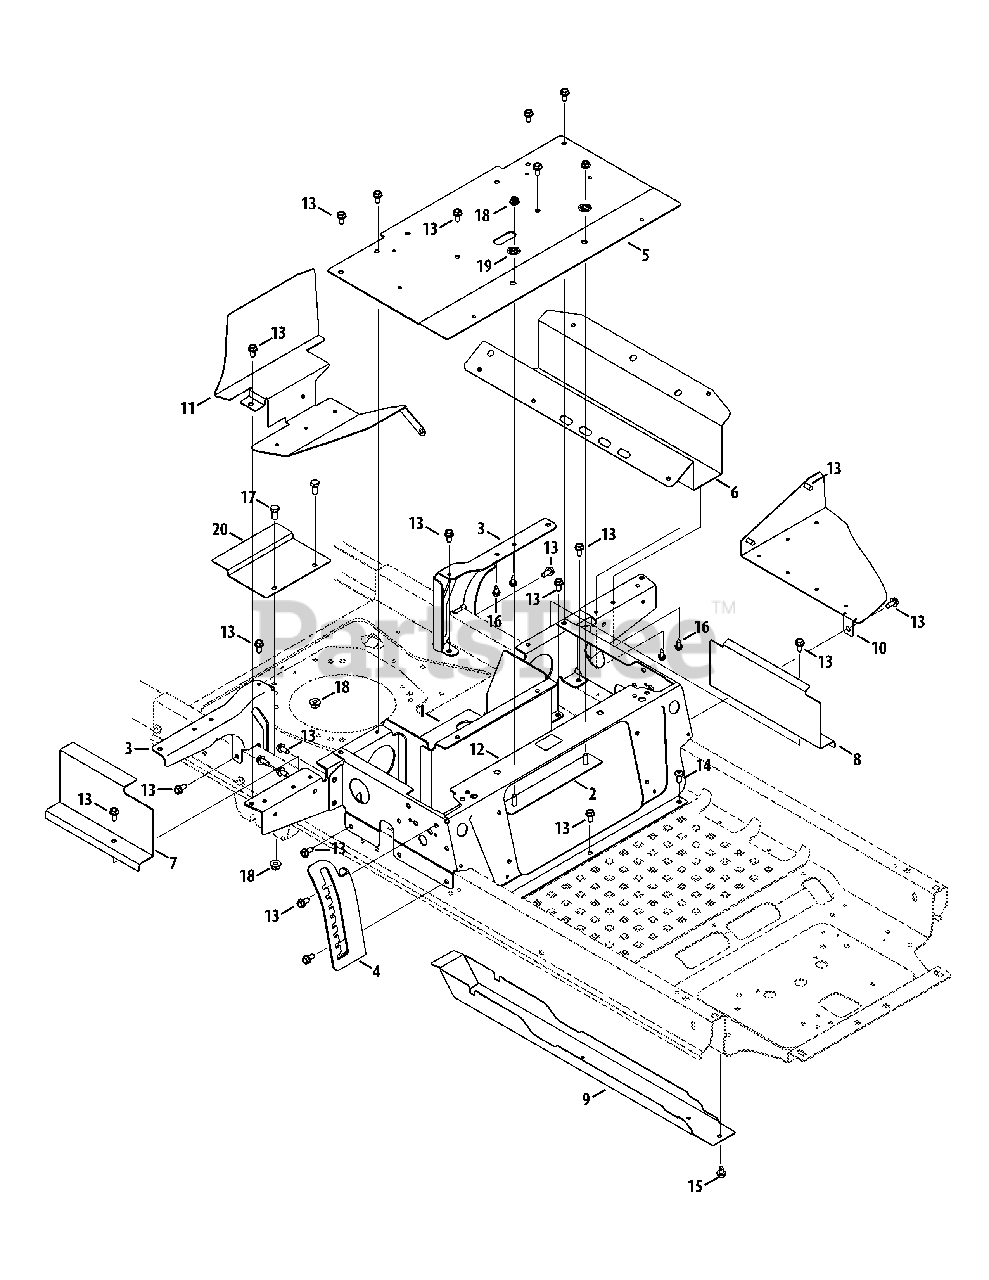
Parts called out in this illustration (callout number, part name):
1	Seatbox Brace, Rear
2	Seat Bolt Weldment
3	Rear Tank Bracket
4	Height Index Bracket
6	Control Panel Mounting Plate
7	Shield Bracket, RH
8	Shield Bracket, LH
9	Shield Bracket, Main Harness
10	Shield Bracket, Control
11	Shield Bracket, RH Pod
13	Hex Washer Screw, 5/16-18 x .750
14	Self Tapping Screw, 5/16-18 x .750
15	Hex Washer Screw, 5/16-18 x .500
16	Hex Washer Screw, 1/4-20 x .625
17	Hex Cap Screw, 5/16-18 x .750
18	Flange Lock Nut, 5/16-18
19	Push Nut, 5/16
20	Support Bracket
